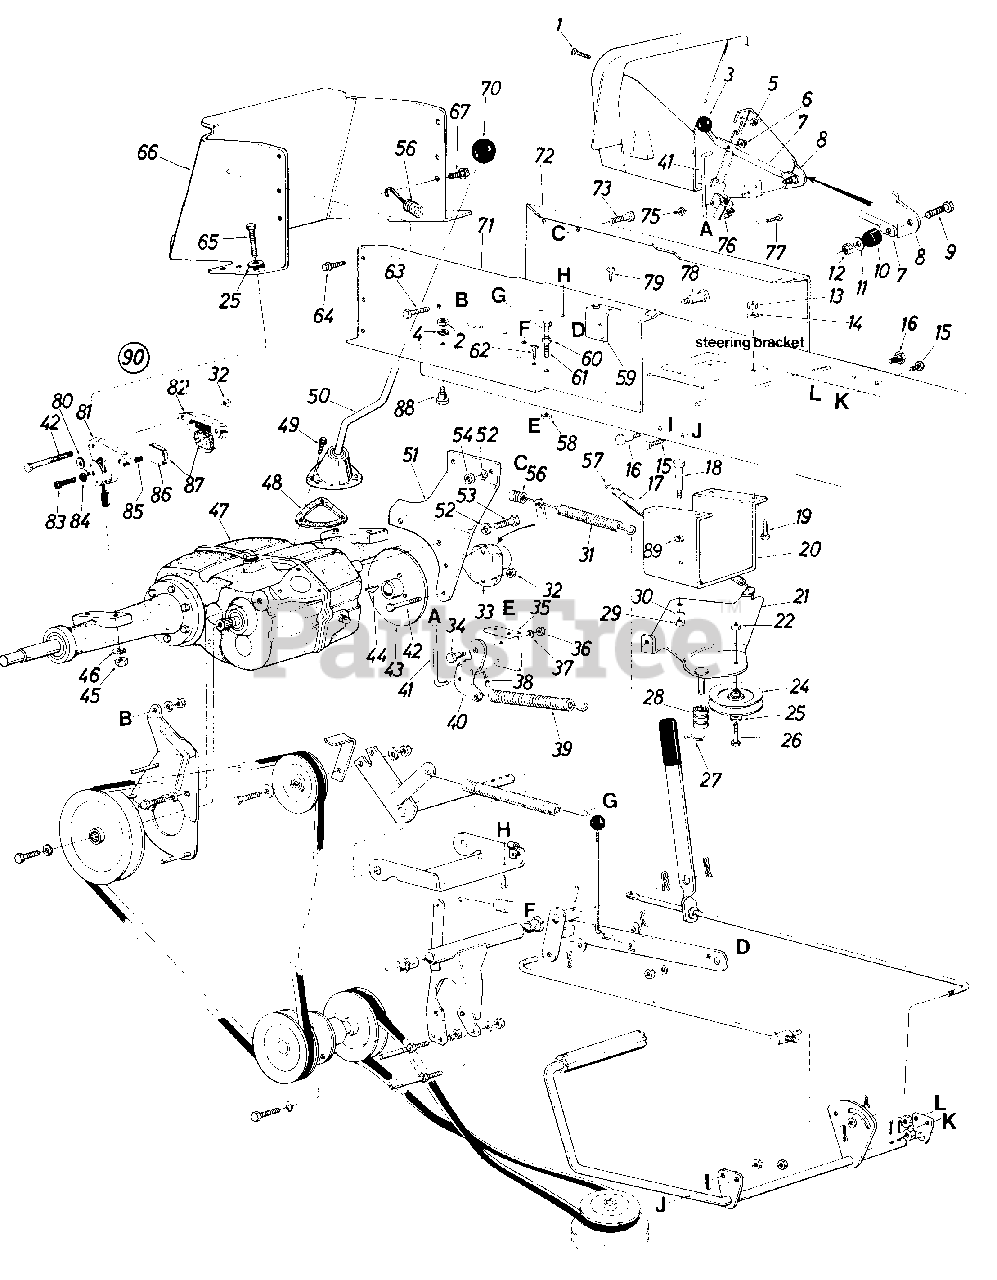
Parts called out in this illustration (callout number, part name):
1	Truss Mach. Scr. 1/4-20 x .50" Lg.
2	Hex Nut 1/4-20 Thd.
3	Knob-Blade Clutch
4	L-Wash. 1/4 I.D.
5	Hex Sems Nut 1/4-20 Thd.
6	Push Cap 1/4" Rod
7	Blade Clutch Lever
8	Deck Clutch Control Brkt.
9	Hex Scr. 1/4-20 x 1.25" Lg.
10	Rubber Wash. .330 I.D. x .87
11	Fl-Wash 1/4" I.D. x .75" O.D. x .057
12	Hex Cent. L-Nut 1/4-20 Thd.
13	Hex Nut 5/16-18 Thd.*
14	L-Wash. 5/16" I.D.
15	Hex Bolt 3/8-16 x .62" Lg.*
16	Shld. Bolt 1/2" Dia. x .335 Lg. 3/8-16
17	Convoluted Conduit .50 I.D. x 4" Lg.
18	Shld. Bolt 7/16 Dia. x .16" 5/1 6-1 8
19	Hex Bolt 5/16-18 x 1.00" Lg.
20	Idler Mtg. Brkt.-Deck
21	Idler Brkt. Ass'y.
22	Hex L-Nut 3/8-16 Thd.
24	4"--"V" Idler Pulley
25	Fl-Wash. 3/8" I.D.
26	Hex Bolt 3/8-16 x 1.25" Lg.
27	Hairpin Cotter 5/16" Rod
28	Spacer
29	Hex Nut 5/16-18 Thd.
30	L-Wash. 5/16" Scr.*
31	Ext. Spring-Brake Rod
32	Hex Cent. L-Nut 3/8-16 Thd.
33	Disc Brake Caliper Ass'y.
34	Shld. Scr. 7/16" Dia. x .16" Lg. 5/16-18
35	1 Parking Brake Cam Mtg. Brkt.
36	Hex Nut 5/16-18 Thd.
37	L-Wash. 5/16" I.D.
38	Hairpin Cotter 5/16" Dia.
39	Ext. Spring-Deck Control
40	Deck Control Pivot Brkt.
41	Deck Control Rod
42	Hex Bolt 3/8-16 x 2.50" Lg.
43	Hub & Disc Ass'y.
44	Hi-Pro Key 3/16 x 3/4" Lg.
45	Hex Nut 3/8-16 Thd.
46	Bell-Wash. .40" I.D.
47	Transaxle
51	Transaxle Support
52	L-Wash. 3/8" Scr.
53	Hex Scr. 3/8-16 x .75" Lg.
54	Hex L-Nut 3/8-16 Thd.
56	Ext. Spring-Brake Return
57	Ext. Spring-Deck Idler Return
58	Hex L-Nut 5/16-18 Thd.
59	Parking Brake Cam Mtg. Brkt.
60	Hex Nut 5/16-18 Thd.
61	Hex Bolt 5/16-18 x 1.5" Lg.
62	Hex Thd. Rolling Scr. 1/4-20 x.50" Lg.
63	Hex Bolt 3/8-16 x .75" Lg.
64	Hex AB-Tap Scr. 5/16 x .75" Lg.
65	Hex Scr. 3/8-16 x 1.50" Lg.
66	Hitch Plate
67	Hex Thd. Rolling Scr. 5/16-24 x .75" Lg.
70	Knob-Transaxle
71	Side Panel Upper Frame- R. H.
72	Side Panel Upper Frame- L. H .
73	Hex Bolt 3/8-16 x .75" Lg.*
75	Hex Nut #10-24 Thd.
76	Safety Switch
77	Truss Mach. Scr. #10-24 x .50" Lg.
78	Shld. Bolt 7/16" Dia. x .16" Lg. 5/16-18
79	Hex Thd. Rolling Scr. 1/4-20 x .50" Lg.
81	Housing with Lever & Pin
83	Pin, Adjuster
84	Nut
85	Pin, Actuator
86	Backing Plate
87	Lining
88	Shld. Bolt .375" Dia. x .180" Lg. 1/4-20 Thd.
89	Wave Washer
90	Disc Brake Ass'y. Comp.
